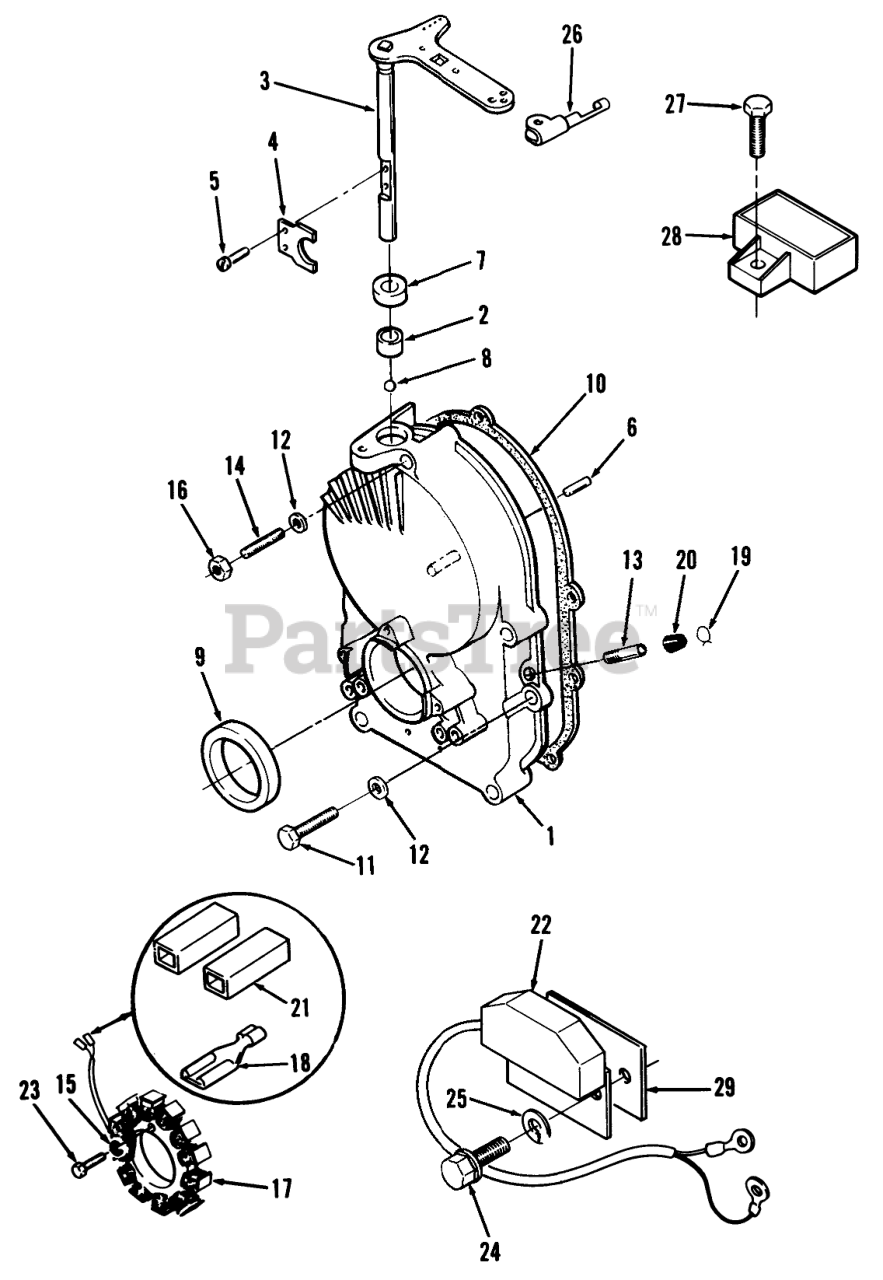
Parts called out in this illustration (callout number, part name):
1	Gearcase (Kit)(Includes Parts Marked)
2	Bearing
3	SHAFT AND ARM
5	Screw, Machine-Pan Head (8-32 x 3/8")
6	PIN-DOWEL
8	Bearing
10	Gasket
11	Bolt
12	WASHER
13	Vacuum Tube
14	Stud, Gear Cover
15	Washer-Lock
16	NUT-GEAR COVER
17	Stator (Includes Terminals)
18	Stator Leads Terminal
19	CLAMP
20	CAP-FUEL OUTLET
21	Body, Terminal Connector Kit (Includes Terminals)
22	Control-Ignition
23	Screw-HH
24	Bolt
25	WASHER-LOCK
27	SCREW-HWH
28	Regulator
29	Insulator
